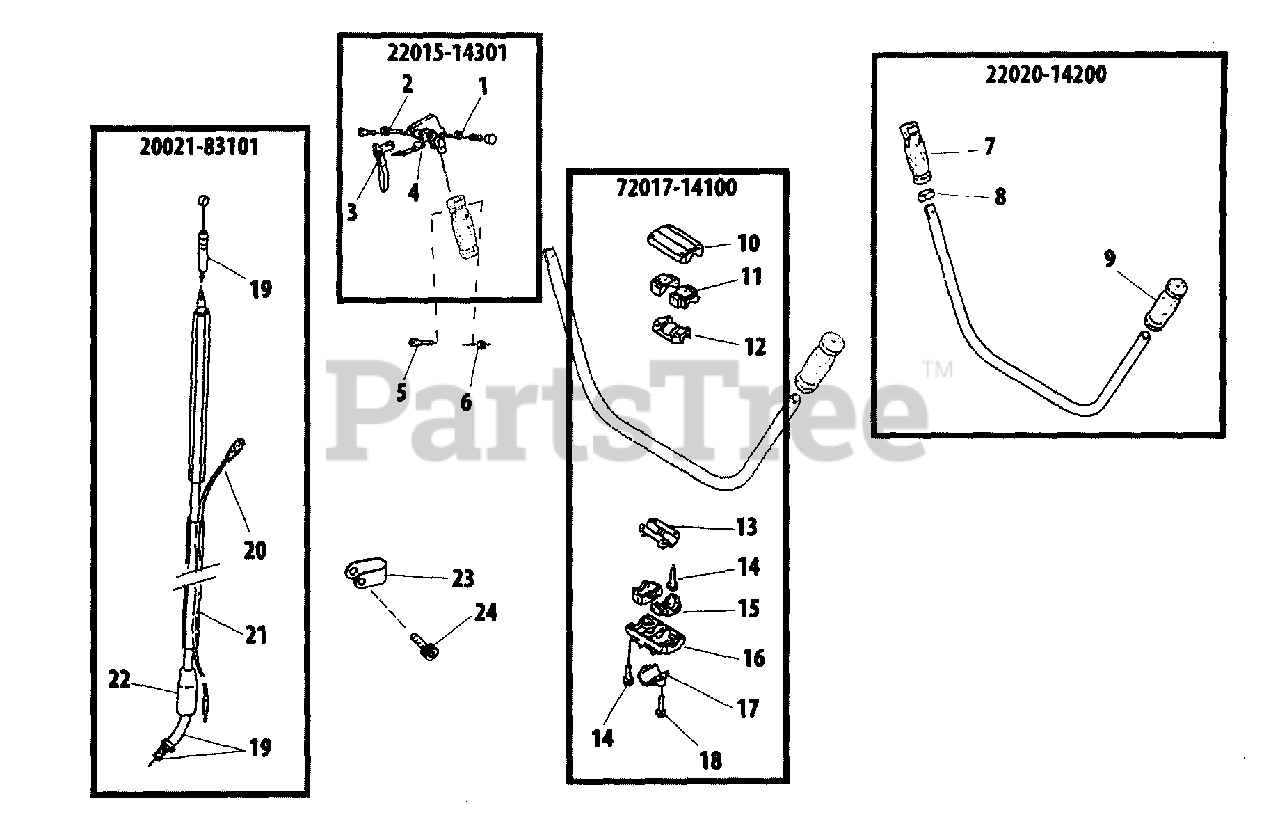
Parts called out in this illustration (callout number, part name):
1	LOCKNUT - 5
2	BOLT
3	TRIGGER, THROTTLE
4	STOPPER, THROTTLE TRIGGER
5	BOLT M4×24
6	NUT, NYLON M4
7	GRIP, RIGHT
8	HOLDER, THROTTLE CABLE
9	GRIP, LEFT
10	CLAMP, UPPER
11	CUSHION, UPPER
12	CLAMP, UPPER
13	CLAMP, LOWER
14	BOLT M5×25
15	CUSHION, LOWER
16	BRACKET, HANDLE Ø28
17	CLAMP, LOWER Ø28
18	SCREW M6×25
19	CABLE, THROTTLE
20	LEAD - GROUND
21	TUBE, PROTECTIVE
22	CAP, CARBURETOR
23	CLAMP
24	BOLT M4×12
20021-83101	CABLE ASSY, THROTTLE
22015-14301	THROTTLE CONTROL ASSY
22020-14200	HANDLEBAR ASSY
72017-14100	BRACKET KIT, HANDLEBAR
